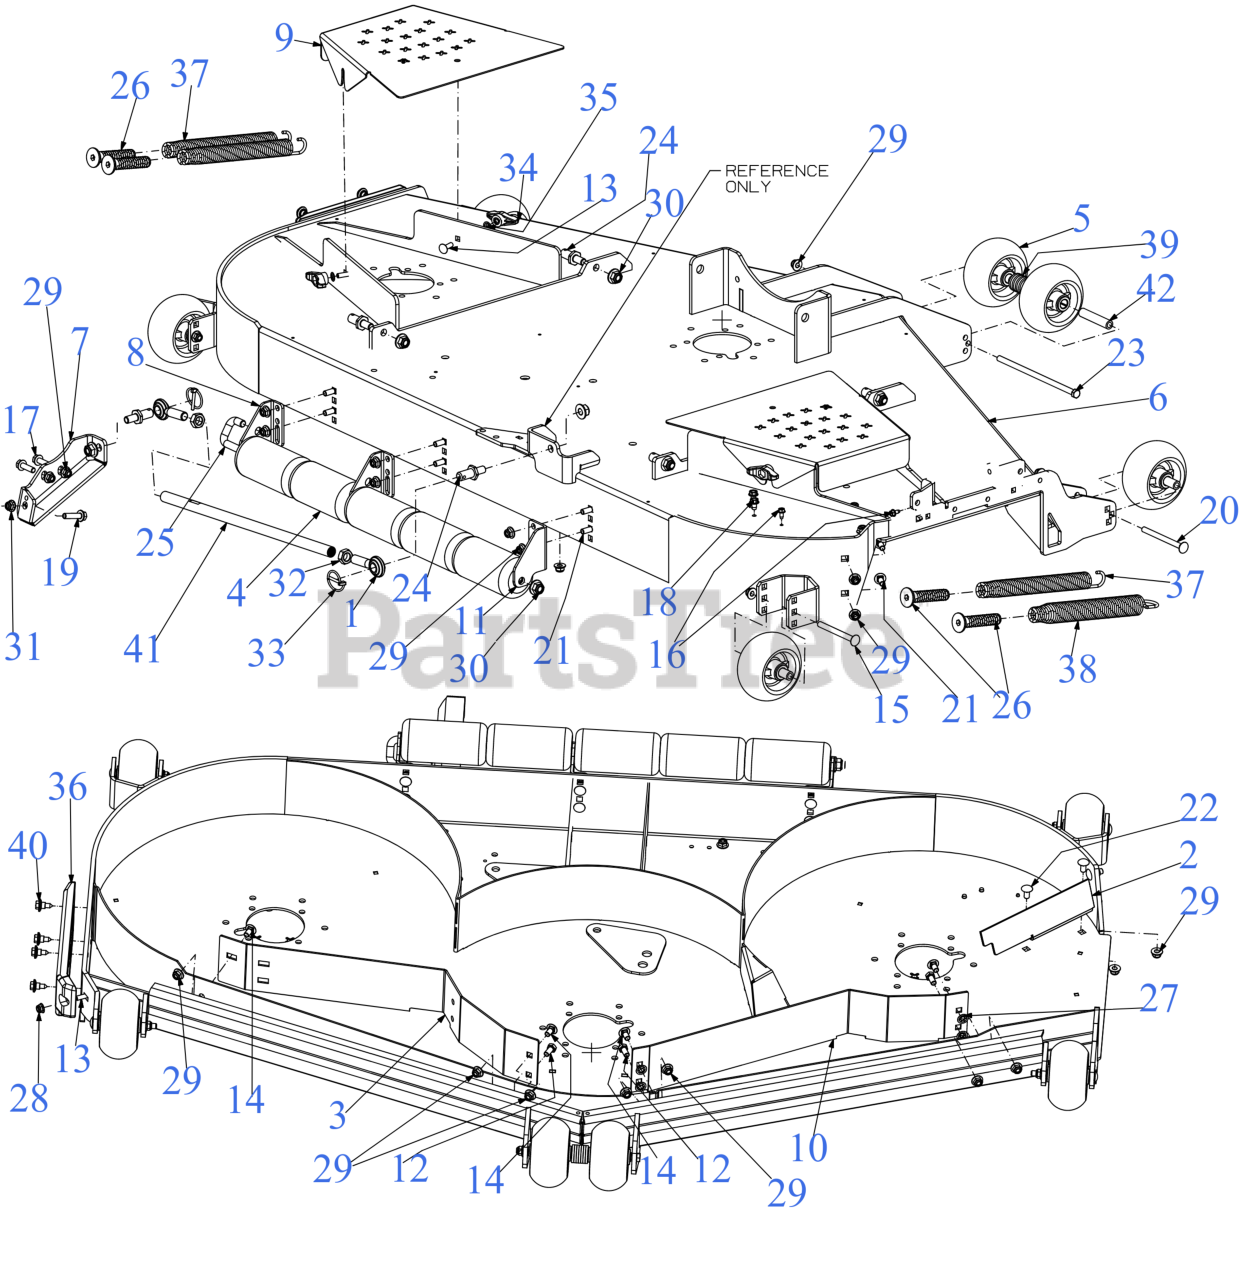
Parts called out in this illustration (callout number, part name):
1	MALE ROD END
2	BAFFLE - CHUTE
3	BAFFLE - 72" ADJ
4	ROLLER ASSEMBLY
5	5" DIA DECK WHEEL COMPLETE
5	WHEEL BUSHING
6	72" FAB DECK SHELL (CUB YELLOW 2)
7	STABILIZER MOUNTING BRACKET
11	REAR ROLLER BRACKET (RH)
12	HEX SCREW 3/8-16 x .75
13	CARRIAGE BOLT 5/16-18 x 1.00
14	CARRIAGE BOLT 3/8-16 x .750 GR5
15	CARRIAGE BOLT 3/8-16 x 4.00 GR5
16	SCREW 1/4-20 X.500
17	SCREW 3/8-16 x 1.25 GR5
18	SCREW 5/16-18 x .500
19	HEX HEAD BOLT (3/8-16:1.50 GR8)
20	CARRIAGE BOLT 3/8-16 x 4.25 GR5
21	CARRIAGE BOLT 3/8-16 x 1.00 GR5
22	CARRIAGE BOLT 3/8-16 x .75
23	SCREW 3/8-16 x 8.5 GR5
25	REAR ROLLER PIN
26	SPRING INSERT SCREW
28	FLANGE LOCK NUT 5/16-18
31	LOCK NUT (3/8-16)
32	HEX JAM NUT 5/8-18
33	LYNCH PIN .1875
34	WING KNOB 5/16-18
36	DECK SKID PLATE (LH)
37	EXTENTION SPRING 1.20 x 11.35
38	EXTENSION SPRING 1.44 OD x 11.36
39	FLAT WASHER
40	SHOULDER SCREW .43X.29X5/16-18 TT
41	TUBE .565 X .750 X 18.75"LG
42	WHEEL SPACER .38ID x 3.04LG
